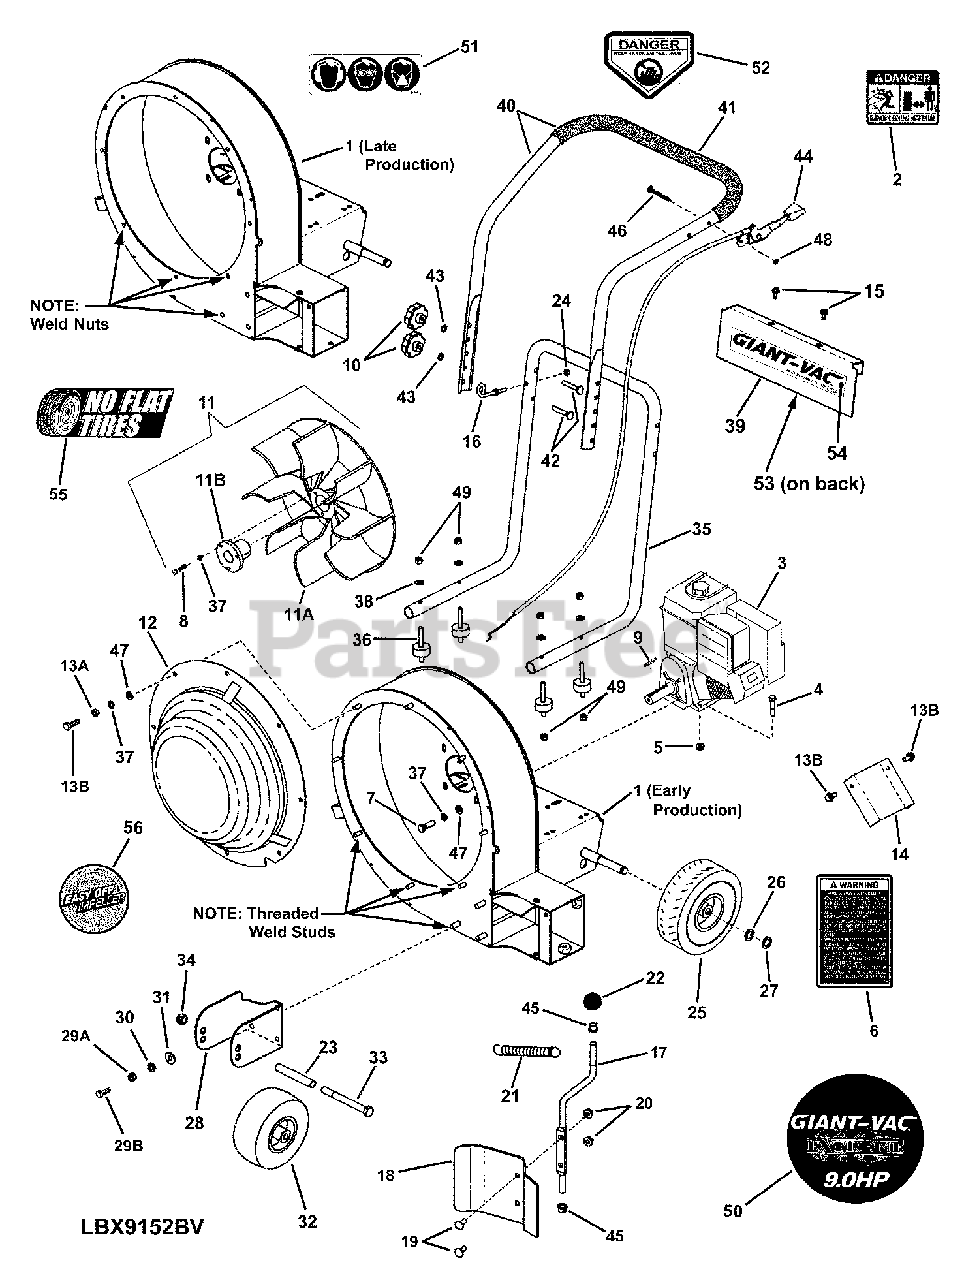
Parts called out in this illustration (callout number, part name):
1	WELDMENT, Housing - Extreme Blower
2	DECAL, Thrown Objects, Large
3	* ENGINE, B&S 9HP Mod 185432-0571-E1
4	SCREW, 5/16-18 x 1-1/2 Hex Head Cap, GR 5
5	NUT, 5/16-18 Hex Flange Lock, GR 5
6	DECAL, Warning - Leaf Blower
7	SCREW, 5/16-24 x 1-1/4" Hex Head Cap, GR 5
8	SCREW, 5/16-18 x 1-1/4" Hex Head Cap, GR 5
9	KEY, 1/4" Square x 2"
10	KNOB, Fluted (5/16-18 thread)
11	ASSEMBLY, 15" 9 Blade Impeller
11A	IMPELLER, Cast, 15" O.D.
11B	HUB, Taper-Lok, Type 1 - P1 x 1.000
12	WELDMENT, Intake Baffle - Extreme
13A	NUT, 5/16-18 Hex, GR 5 or B
13B	SCREW, 5/16-18 x 3/4" Hex Head Cap, GR 5
14	DEFLECTOR, Side Air
15	SCREW, 5/16-18 x 5/8" Hex Washer Self-Tap
16	GUIDE, Rope (1/4-20 thread)
17	ROD, Door Front/Side Discharge
18	DOOR, Forward Air Control
19	SCREW, 1/4-20 x 3/4" Short Sq. Neck Carriage
20	NUT, 1/4-20 Hex Flange Lock, GR 5
21	SPRING, Extension
22	KNOB, Ball - 3/8-16 Metal Insert
23	SLEEVE, Axle
24	NUT, 1/4-20 Hex Center Lock, GR 5 or B
25	ASSY., Wheel & Tire 4.10/3.50-4 "Flatfree"
26	WASHER, .64 x .99 x .05 Flat
27	RING, External Retaining
28	BRACKET, Front Wheel Mounting
29A	NUT, 3/8-16 Hex, GR 5 or B
29B	SCREW, 3/8-16 x 1" Hex Head Cap, GR 5
30	WASHER, 3/8" Split Lock
31	WASHER, 3/8" Flat
32	ASSY., Tire & Wheel 9 x 3.50-4 "Flatfree"
33	BOLT, 1/2-13 x 5" Hex Head Cap
34	NUT, 1/2-13 Hex Center Lock, GR 5
35	HANDLE, Lower Folding - Wide - Blower
36	MOUNT, Vibration (5/16-18, both ends)
37	WASHER, 5/16" Split Lock
38	WASHER, 5/16" Curved
39	DASH PANEL, Blower - Wide
40	ASSY, Upper Handle & Grip
41	GRIP, 1.0 x 21-1/2" Foam
42	BOLT, 5/16-18 x 2", Curved Head Sq. Neck
43	WASHER, 5/16" Internal Tooth Lock
44	THROTTLE CONTROL, 29.25/2.12
45	BEARING, 3/8" Clip
46	SCREW, 1/4-20 x 2" Hex Head Cap, GR 5
47	WASHER, .34 x .69 x .08 Flat
48	NUT,1/4-20 Hex Nyloc
49	NUT, 5/16-18 Hex Nyloc
50	DECAL, 9 HP Extreme
51	DECAL, Personal Protection
52	DECAL, Danger, Cut Finger
53	DECAL, GIANT-VAC (Small)
54	DECAL, GIANT VAC
55	DECAL, No Flat Tire
56	DECAL, Easy Off Impeller
